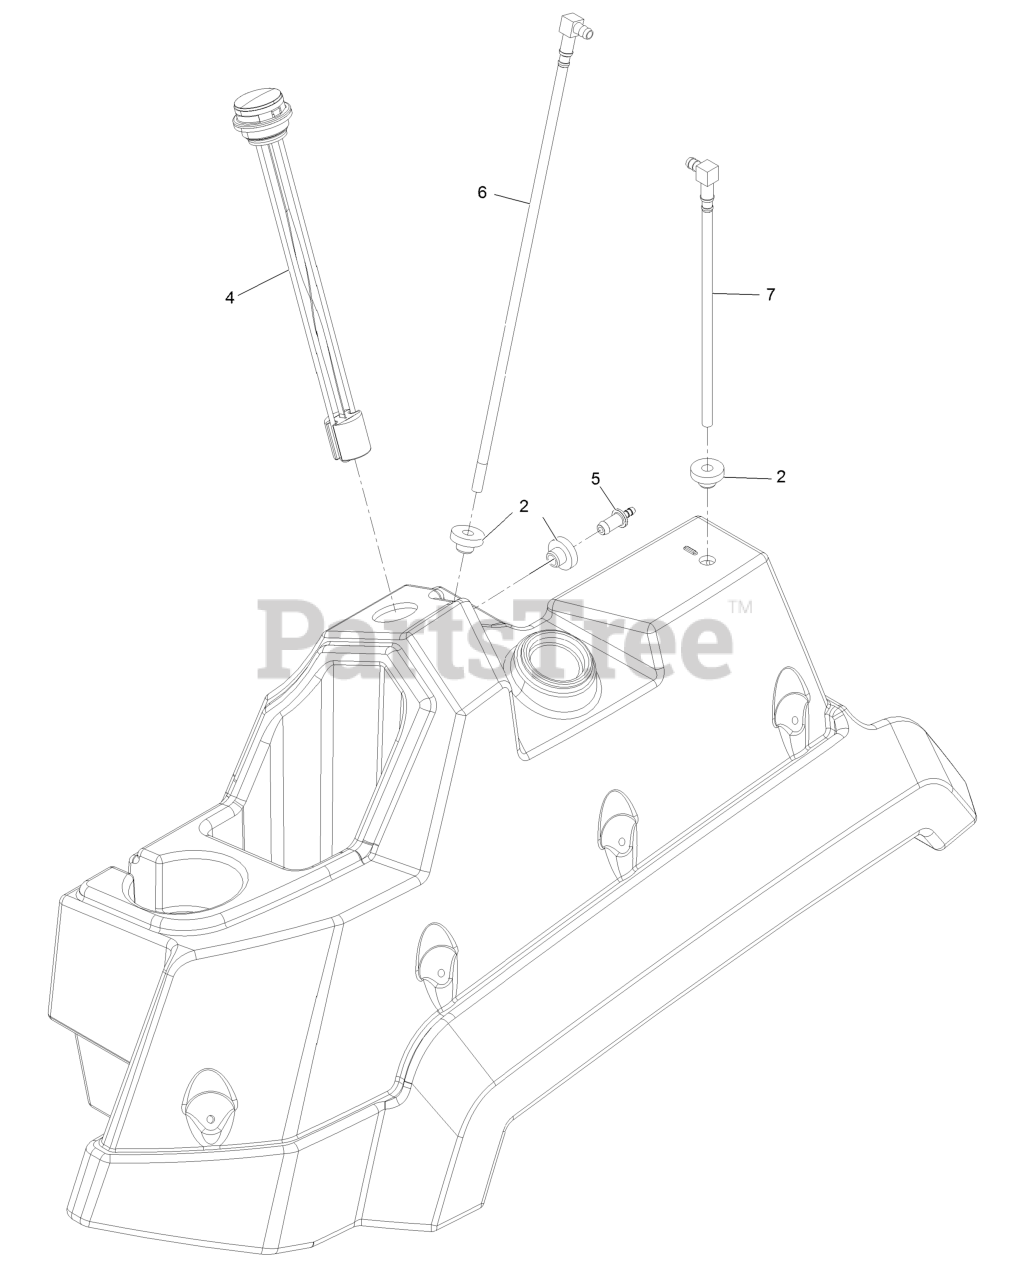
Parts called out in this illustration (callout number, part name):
2	Bushing
4	Gauge-Fuel
5	Fitting-Orifice, Straight
6	Pick-Up-Fuel
7	Return-Fuel
